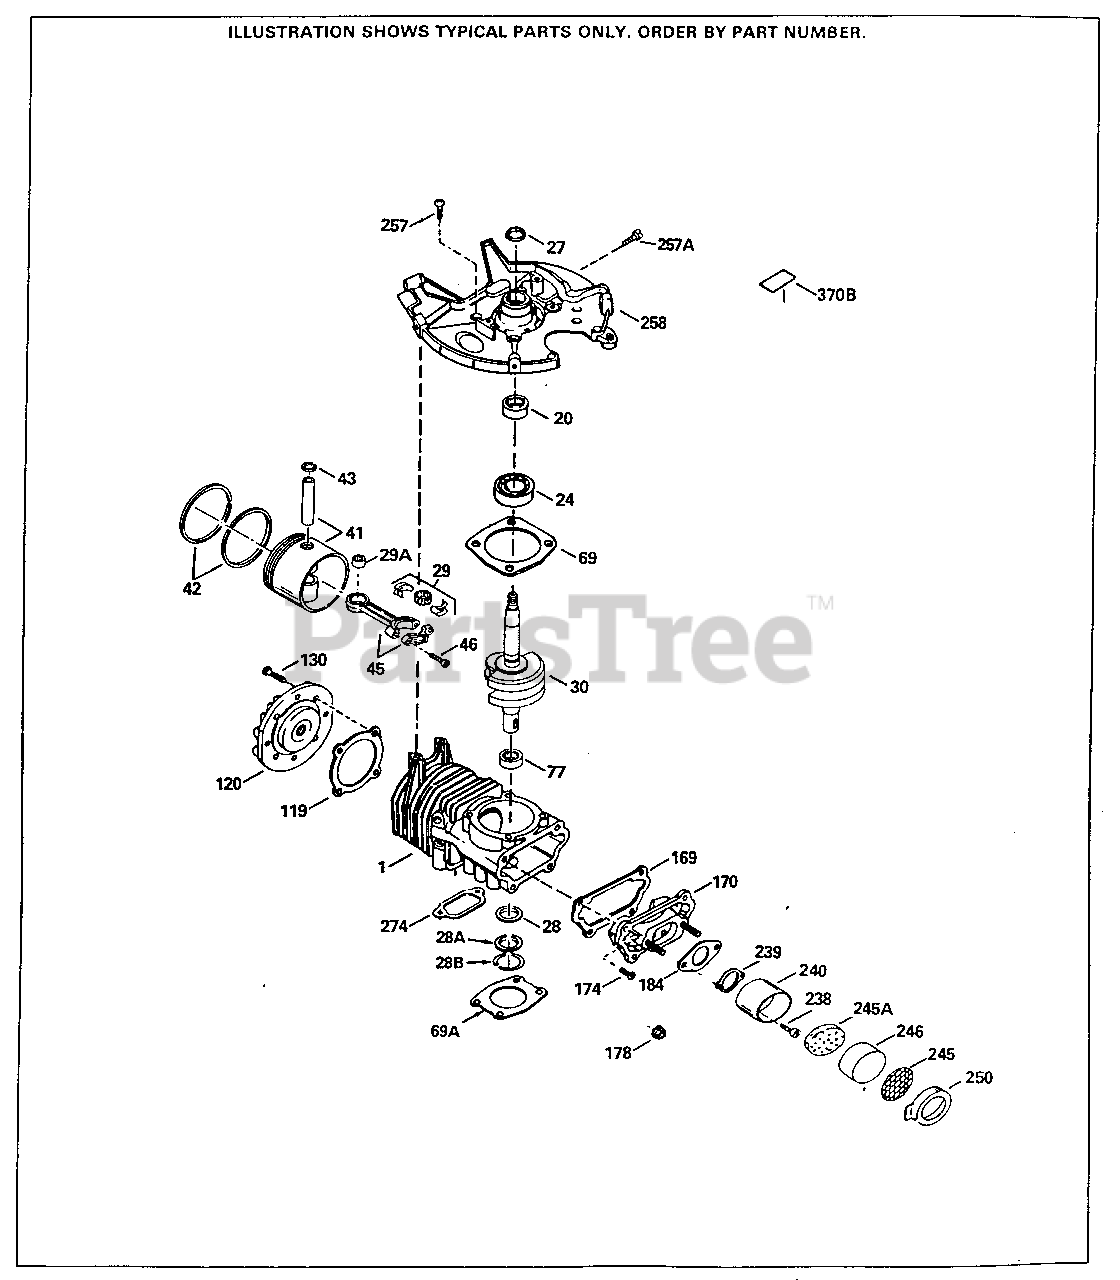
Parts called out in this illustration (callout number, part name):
1	"Cylinder
24	Bearing, Ball
27	Seal, Crankshaft
28	Seal, Crankshaft
28A	Retainer, Crankshaft seal
28B	Ring, Crankshaft seal retainer
29	Bearing & Liner Set, Needle 37 needle s
29A	Bearing, Needle
30	Crankshaft
41	Piston & Pin Assy.
42	Ring Set, Piston
43	Ring, Piston pin retaining
45	Rod Assy., Connecting Incl. 29, 29A& 46
46	Screw, Connecting rod
69	Gasket, Housing base
77	Bearing, Needle
119	Gasket, Cylinder head
120	Cylinder Head
130	Screw, 1/4-20 x 3/4"
169	Gasket, Cover plate
170	Plate Assy., Reed & Cover
174	Screw, 10-24 x 1/2"
178	Nut, Flange whiz-lock, 1/4-28
184	Gasket, Carburetor
238	Screw, 10-32 x 5/8"
239	Gasket, Air filter
240	Body, Air filter
245	Air Filter
245A	Air Filter
246	Air Filter
250	Cover, Air filter
257	Screw, Torx T-30, 1/4-20 x 5/8"
258	Blower Housing Base
274	Gasket, Exhaust
370B	Decal, Warning
